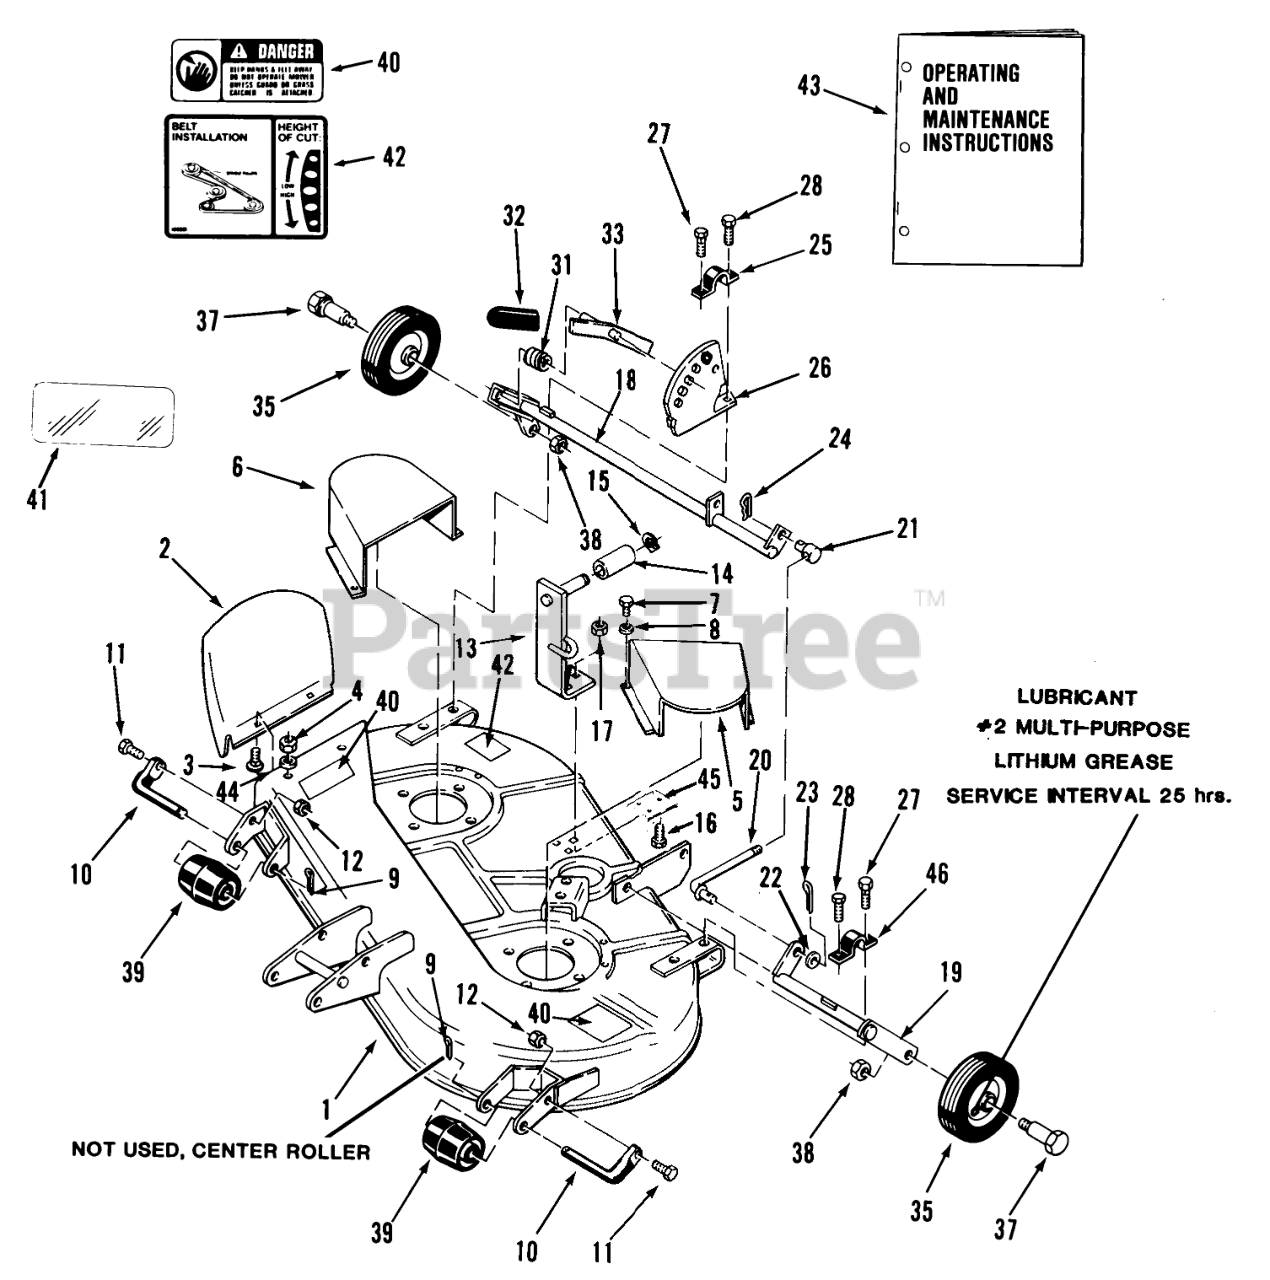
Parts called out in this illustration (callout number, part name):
1	Mower Deck
2	Chute Extension
3	Bolt
4	Nut
5	COVER R
6	COVER R
7	Bolt
8	WASHER
9	Cotter Pin
10	ROLLER-SHAFT
11	Bolt
12	Nut
13	GUIDE BRACKET ASSY R
14	SPACER
15	Snap Ring
16	BOLT HEX SPECIAL
17	NUT
18	Gage Wheel Support RH
19	WA GAG WHL R
20	ROD CONNECTING
21	TRUNNION
22	Washer
23	Pop Rivet
24	Hairpin
26	Quadrant
27	Bolt
28	Bolt
31	SPRING-COMPRESSION
33	Lever
35	WHEEL
37	BOLT-SHOULDER
38	NUT
39	Roller
40	Danger Decal
41	DECAL-OVERLAY
42	DECAL-BELT&HEIGHT
43	Owner-s & Maintenance Instructions
44	WASHER 5/16 SAE
45	PLATE-REINFORCING R
46	CLAMP B
